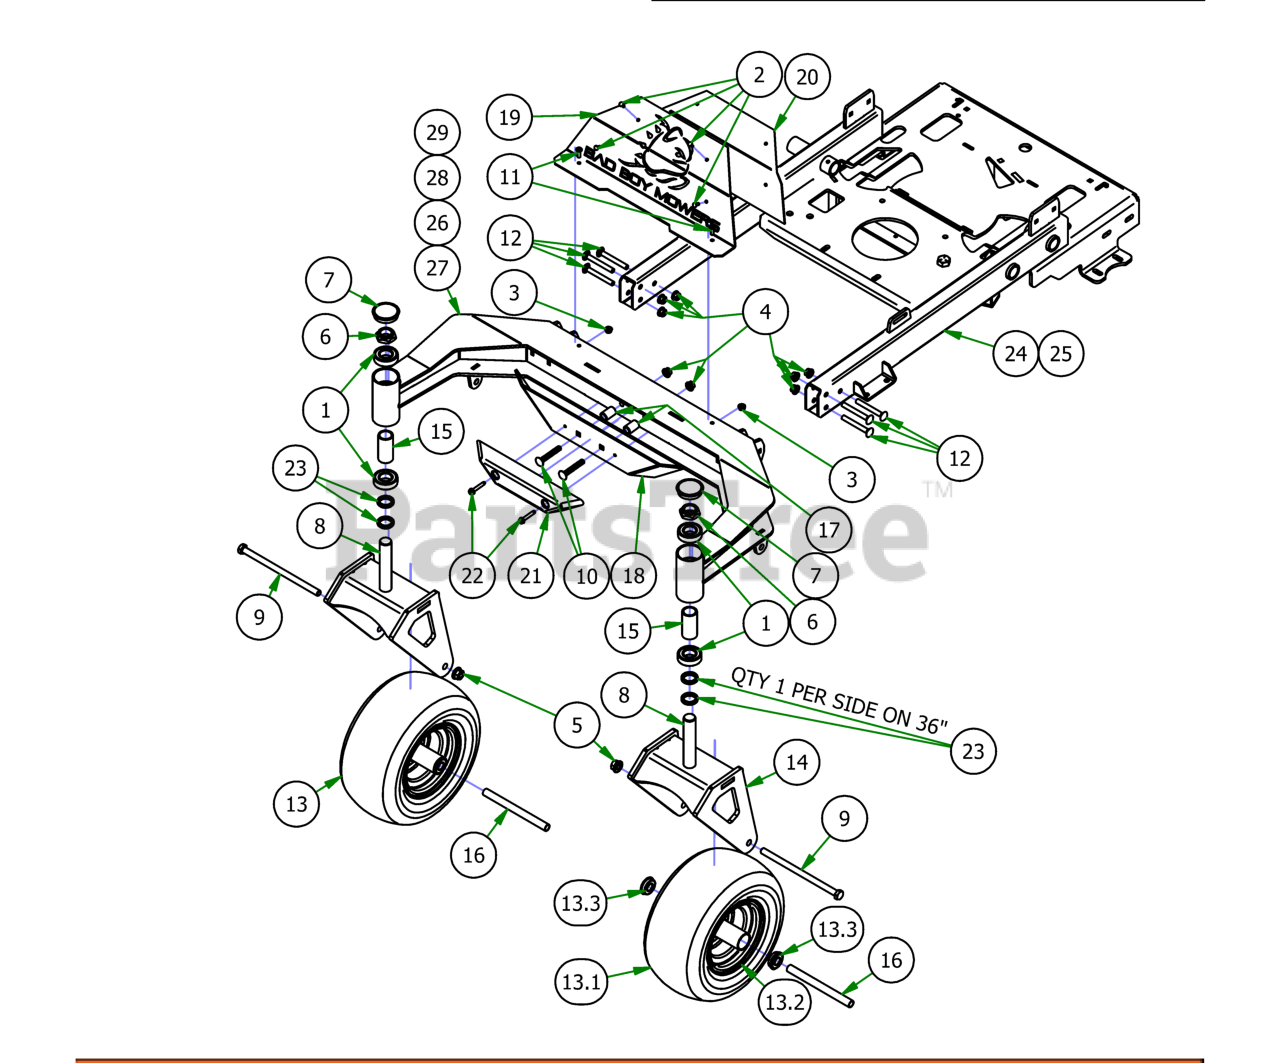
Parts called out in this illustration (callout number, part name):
1	1641 BEARING W/2 CONTACT RUBBER SEALS
2	3/16 Rivet for .126-.25 THK
3	1/4-20 Nylon Insert flange Nut
4	3/8" Nylock Flange Nut
5	1/2-13 NYLON INSERT FLANGE LOCKNUT ZINC
6	1"-14 NYLON INSERT JAM LOCKNUT ZINC
7	2017 Bearing Cover
8	1"-14 X 5-1/2 HEX CAP SCREW (GR.8) ZINC YELLOW
9	1/2-13 X 8-1/2 HEX CAP SCREW (GR.5) ZINC
10	3/8" x 2 1/2" Carriage Bolt
11	1/4"-20 x 3/4 Black Oxide 18-8 Stainless Pan Head
12	3/8-16 X 3 CARRIAGE BOLT ZINC GR5
13	13x6.5-6 Black Tire and Wheel Assembly
13.1	13 x 6.50 - 6 Tire
13.2	Front Tire Rim
13.3	Ball Bearing w/Retainer, 99502H-NR, .625 Bore x 1.375 OD x .4375 Width
14	2019 Stand-on Front Fork Weldment
15	2016 Front Bearing Spacer
16	Front Wheel Spanner
18	2019 Stand On Front Bumper Plate
19	2019 Stand On Exhaust Shield
20	2019 Stand On Exhaust Backer Plate
21	Bumper EZT
22	1/4" x 1 1/2" Self Tapping Screw
23	Spacer, 1x1.375x.25
24	2019 Stand On Frame Weldment
25	2020 36 Stand On Frame Weldment
26	2020 36 Stand-On Front End Weldment
27	2019 Stand-On 48 Front End Weldment
28	2019 Stand-On 54 Front End Weldment
29	Stand-On 61 Front End Weldment
